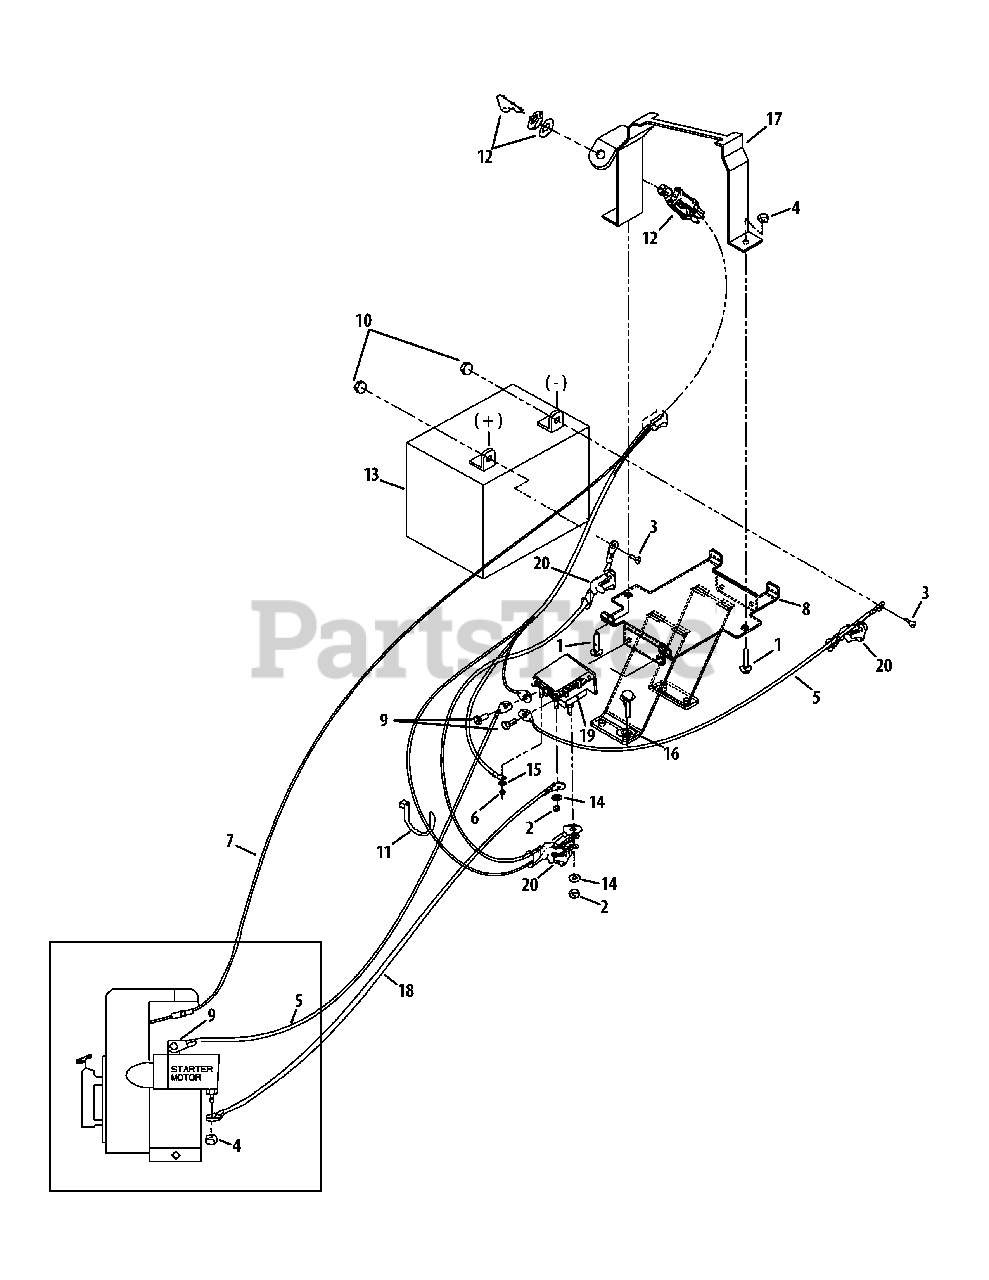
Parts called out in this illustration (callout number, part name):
1	Carriage Screw 1/4-20 x 1.25
2	Hex Nut 5/16-24
3	Flange Screw 1/4-20 x .625
4	Hex Locknut 1/4-20
5	Cable (Ground Wire)
6	Hexlock Washer Nut, 10-32
7	Electric Start Harness
8	Battery Bracket Assembly
9	Self-tapping Screw 1/4-20 x .5
10	Hex Nut 1/4-20
11	Cable Tie
12	Ignition Switch
14	Lock Washer 5/16
15	Lock Washer #10
16	External Lock Washer 5/16
17	Keyswitch Clamp
18	Cable (Solenoid to Starter Motor)
19	Solenoid
20	Insulating Boot
